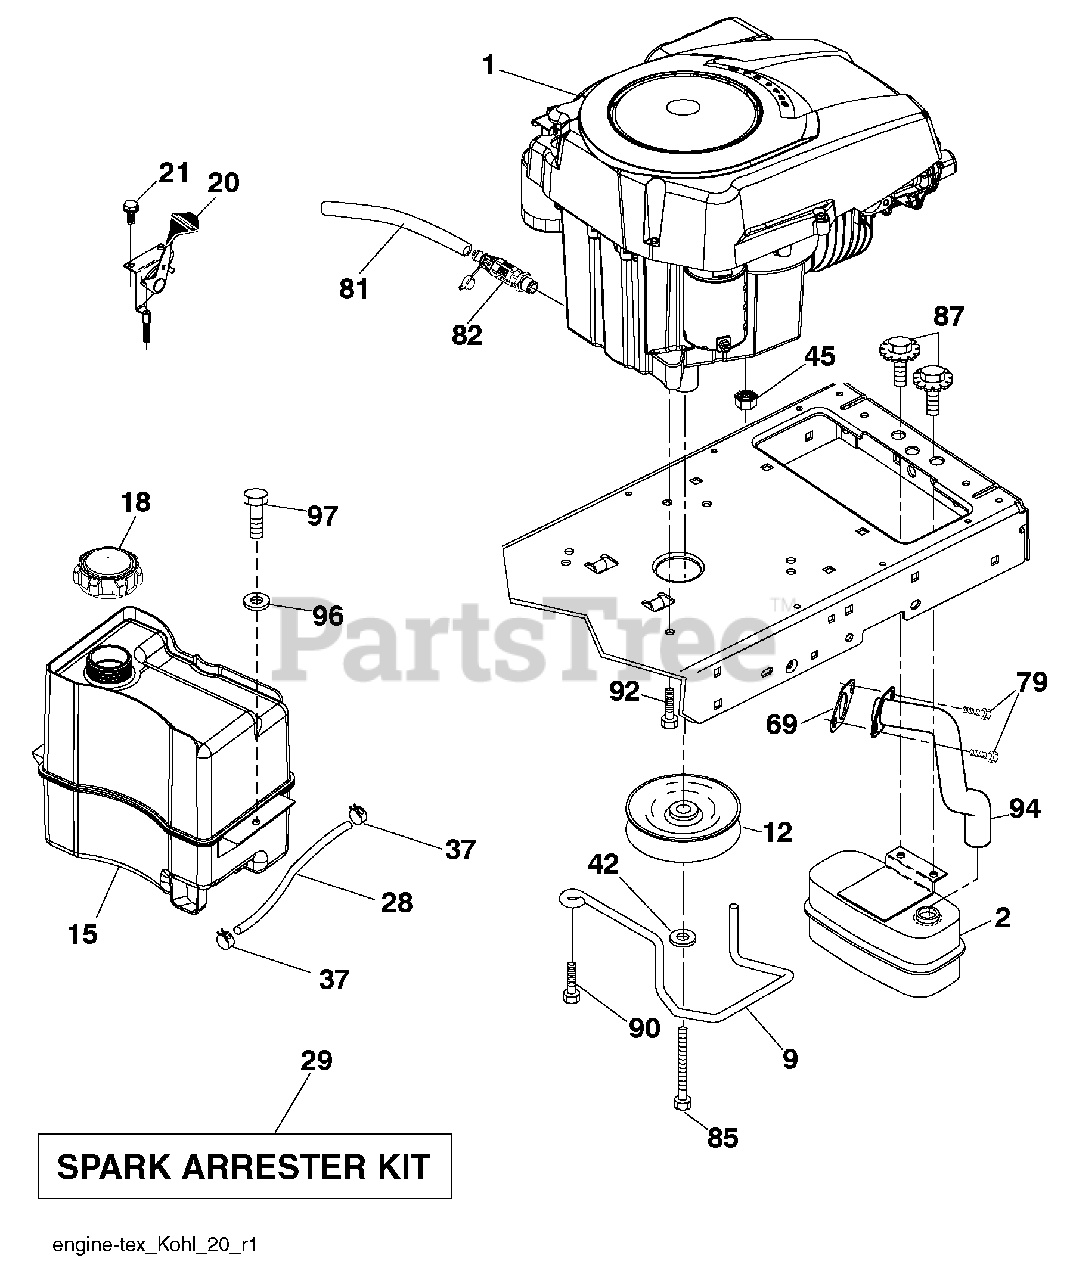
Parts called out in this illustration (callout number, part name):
9	Keeper Belt Engine
12	Pulley Engine
15	Tank Fuel
18	Cap Asm
20	Control Throttle/Choke
21	Screw #10 x 0.750 BOS Thread
28	Fuel Line
29	Spark Arrester Kit
37	Clamp Hose
42	Washer Lock 7/16
45	Nut Keps Hex 1/4-20 unc
79	Screw Socket Head
81	Tube Drain Oil Easy
82	Valve Drain Oil
85	Bolt Hex 7/16-20 x 4 x Gr. 5-1.5 Thr
87	Bolt 5/16-18 unc x 3/4 w/Sems
90	Screw 3/8-16 x 1
92	Screw 3/8-16 x 1
94	Tube Exhaust
96	Washer 9/32 x 7/8 x 16 Ga.
97	Screw Hexwsh Thdrol 1/4-20 x 3/4
